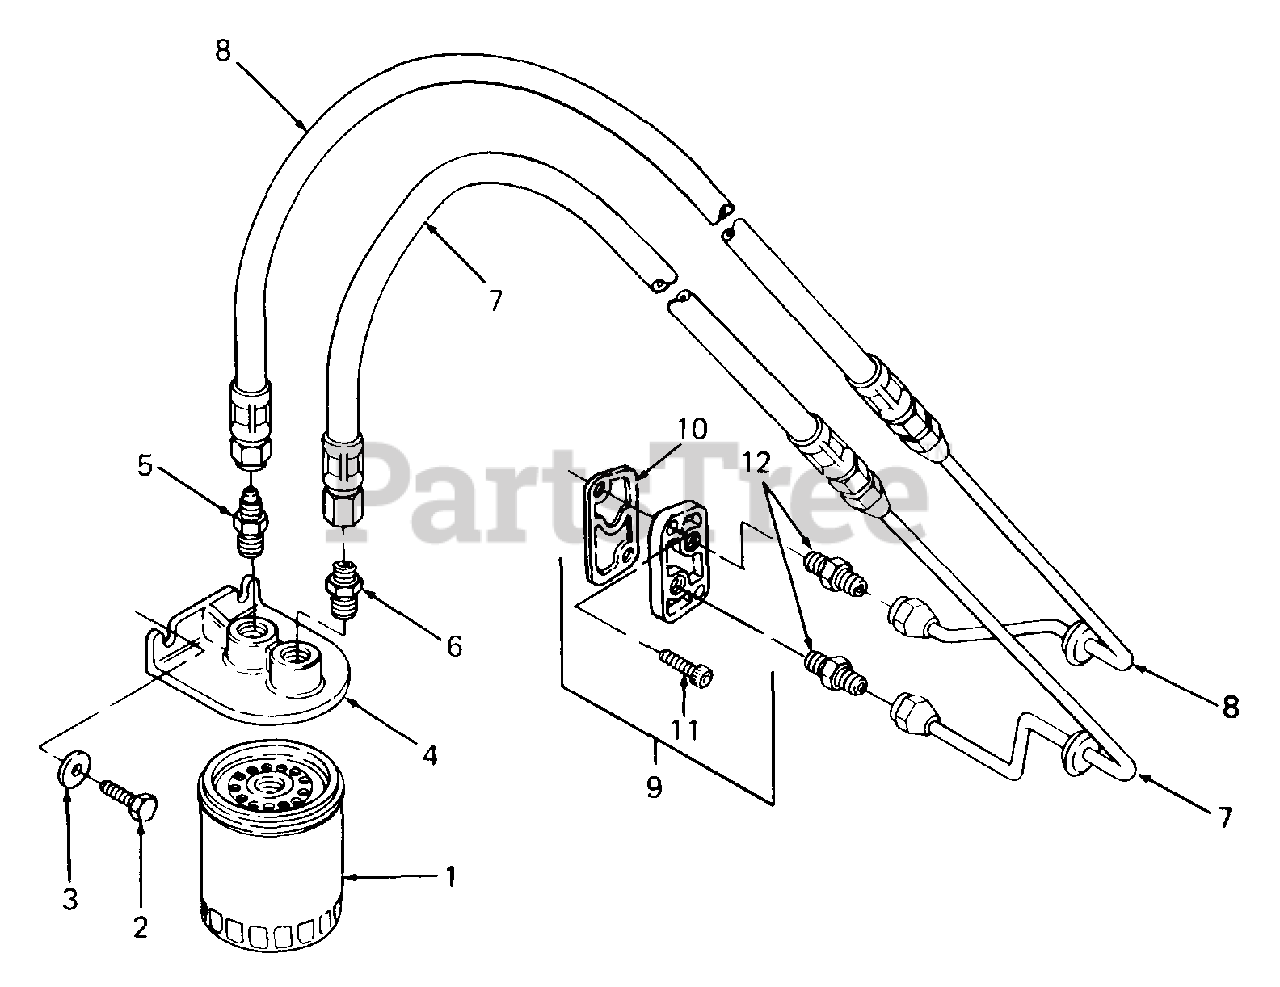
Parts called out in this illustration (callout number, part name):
1	Oil Filter
2	Screw, Hex Cap, 5/16-18 x 1.0 Lg GR5
3	Washer, Bell, .380 x .88 x .060 Thk
4	Adapter, Remote Oil Filter
5	Nipple, Hexagon
6	Connector, Reducing
7	Oil Line - 20.5 Long
8	Oil Line - 22.5 Long
9	Kit, Oil Filter Cover
10	Gasket, Oil Filter Cover
11	Screw, Hex Socket Hd Cap, 5/16-18 x 1.25 Lg
12	Connector, Reducing
